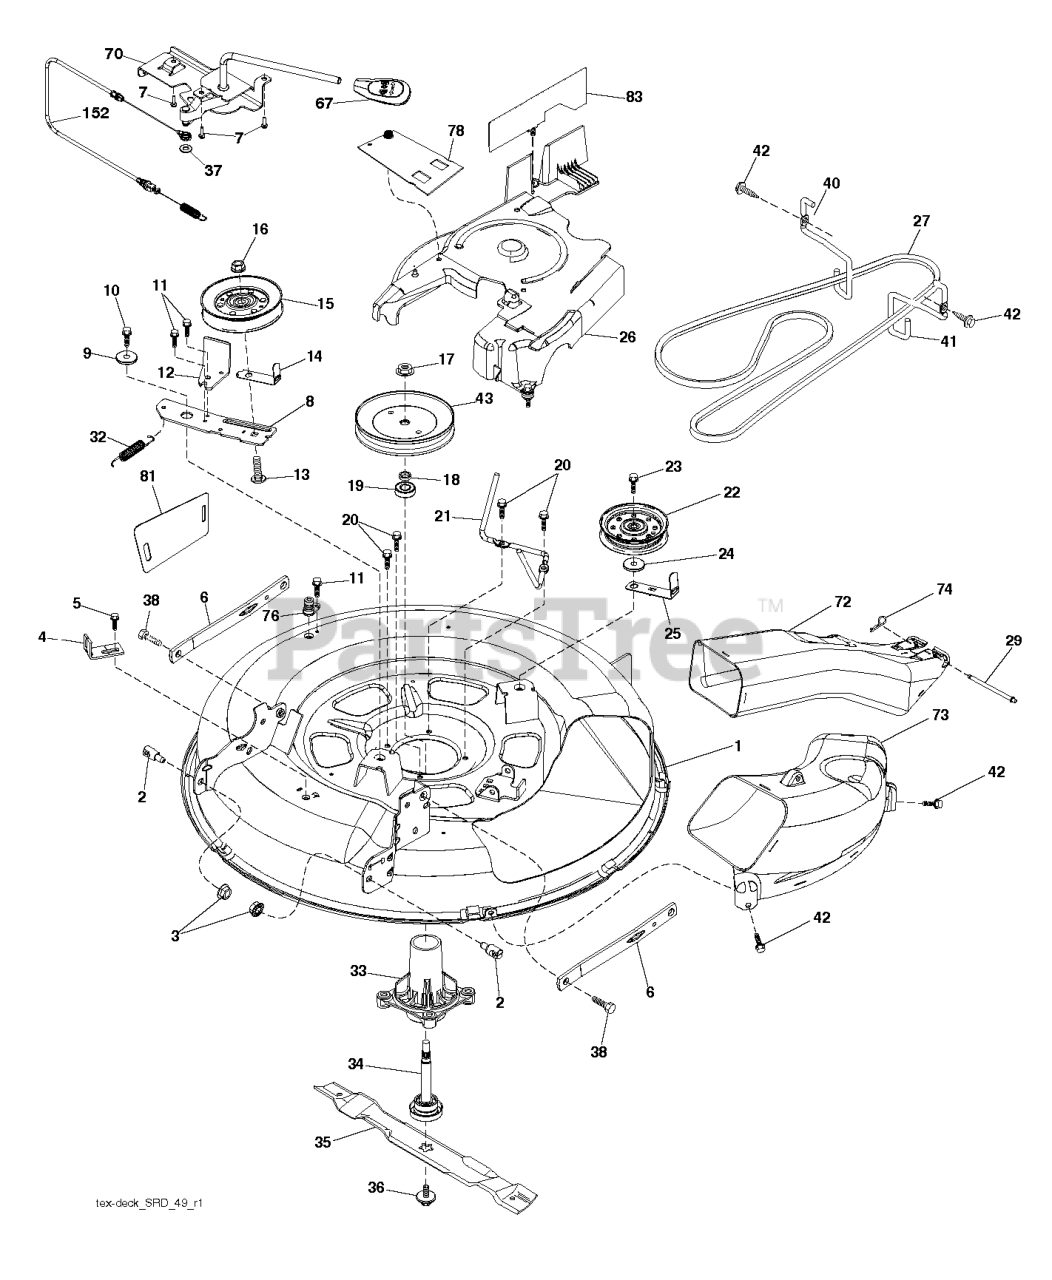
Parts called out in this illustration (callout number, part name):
1	DECK.WELDMENT.30"SRD.BLACK
2	STUD.FASTNER.W/ANTI-ROTATE
3	NUT LOCK HEX FLANGE 5/16-18
4	BRACKET.CLUTCH.CABLE
5	BOLT.5/16HEX.WHS.HD
6	ARMS.SUSP.MOWER.REAR.SRD
7	SCREW.#10 X 0.750.BOS
8	ARM.IDLER.30"SRD
9	SPACER.RETAINER
10	SCREW 3/8-16X1
11	SCREW.1/4-20X5/8
12	RP ARM.BRAKE.MOWER.38"LH.TEX
13	BOLT.3/8-16X1.50
14	KEEPER, BELT IDLER
15	PULLEY.IDLER.4.25
16	NUT LOCK FLG 3/8-16 UNC
17	NUT.FLANGE.LOCK.TOP
18	WASHER.SPACER.MANDREL
20	SCREW, WASHER HEAD
21	KEEPER.BELT.MANDREL.30"
22	PULLEY.IDLER.FLAT.UNPLATED
23	SCREW LT
24	WASHER
25	KEEPER.BELT.30"SRD
26	COVER.ASM.MANDREL.30"
27	V-BELT.DRIVE.MOWER.30"
29	PIN.HINGE.30".SRD
32	SPRING RETURN
33	RP.HOUSING.MANDREL.4PT.
34	SHAFT.ASM.MDRL.N/GREASE.38
35	BLADE.MOWER.BAGGING.30"
36	BOLT.WASHER.ASM.7/16-2
37	WASHER
38	BOLT.SHOULDER
40	KEEPER.BELT.ENGINE.LH.LT.SRD
41	KEEPER.BELT.ENGINE.RH.LT.SRD
42	SCREW, 3/8-16X3/4
43	PULLEY, MANDREL 6.5 PD
67	HANDLE.CLUTCH.CABLE.LT
70	CLUTCH.ASM.MANUAL.LT.PRED
72	CHUTE.UPPER.SRD.30R"
73	CHUTE.LOWER.SRD.30R"
74	RETAINER-SPRNG RB
76	PORT.WASHOUT
78	GUARD ARM CLUTCH
81	SHIELD SUSPENSION
152	CLUTCH CABLE
